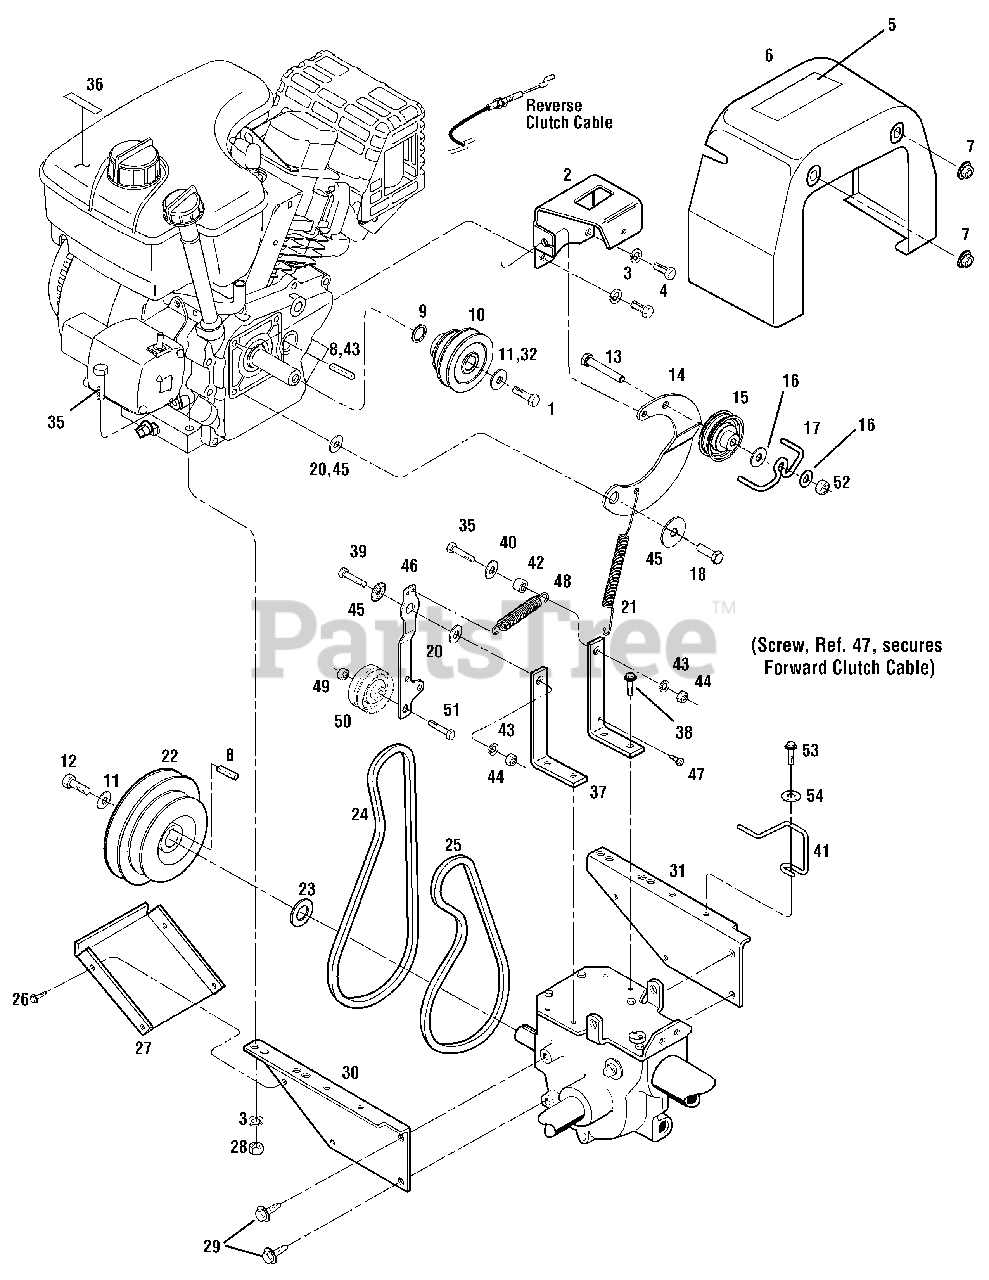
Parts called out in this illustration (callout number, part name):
1	Screw, 3/8-24 x 1.75 (for Models 663E & E663E)
1	Screw, 5/16-24 x 1.125 (for model 665B)
4	Hex Hd. Screw, 5/16-24 x 1/2
5	Decal, Hot Surfaces/Belt Warning
7	Flange Lock Nut, 5/16-18
8	Key, 3/16 x 1-1/2 (for model 665B)
10	Pulley, Engine Drive (for Models 663E & E663E)
10	Pulley, Engine Drive (for model 665B)
11	Belleville Washer (for model 665B)
12	Hex Hd. Screw, 5/16-24 x 1-1/8
13	Hex Hd. Screw, 5/16-18 x 2
14	Reverse Idler Arm
15	Pulley, Reverse Idler
16	Flat Washer, 5/16
17	Belt Guide, Wire Formed
18	Hex Head Screw, 5/16-24 x 1
19	Washer, Shoulder
20	Washer, Flat 1-1/8
21	Spring, Reverse Return
22	Transmission Pulley
23	Support Washer
24	Reverse Clutch Belt
25	Forward Clutch Belt
26	Self-tapping Screw #10-32 x 1/2
28	Hex Flange Nut, 5/16-18 (specify GRADE 5 if ordering part locally)
29	Hex Flange Screw, 5/16-18
32	Bell Washer (for Models 663E & E663E)
35	Hex Hd. Screw, 5/16-18 x 2-1/4
36	Decal, Stabilization
37	Mounting Bar
38	Hex Flange 5/16-18 x .75
39	Hex Hd. Screw, 5/16-18 x 1-1/2 (specify GRADE 5 if ordering part locally)
40	Flat Washer, 5/16
41	Belt Guide, Pony
42	Pivot Bushing
43	Key, .188 x 1.75 (for Models 663E & E663E)
44	Hex Nut, 5/16-18
45	Washer, Shoulder
47	Screw, self tapping, #10-24
49	Hex Locknut, 5/16-18
50	Idler Pulley, Forward
51	Screw, 3/8-16 x 1-3/4
52	Hex Lock Nut, 5/16-18
53	Screw, 1/4-20 x 3/4
54	Flat Washer, 1/4
